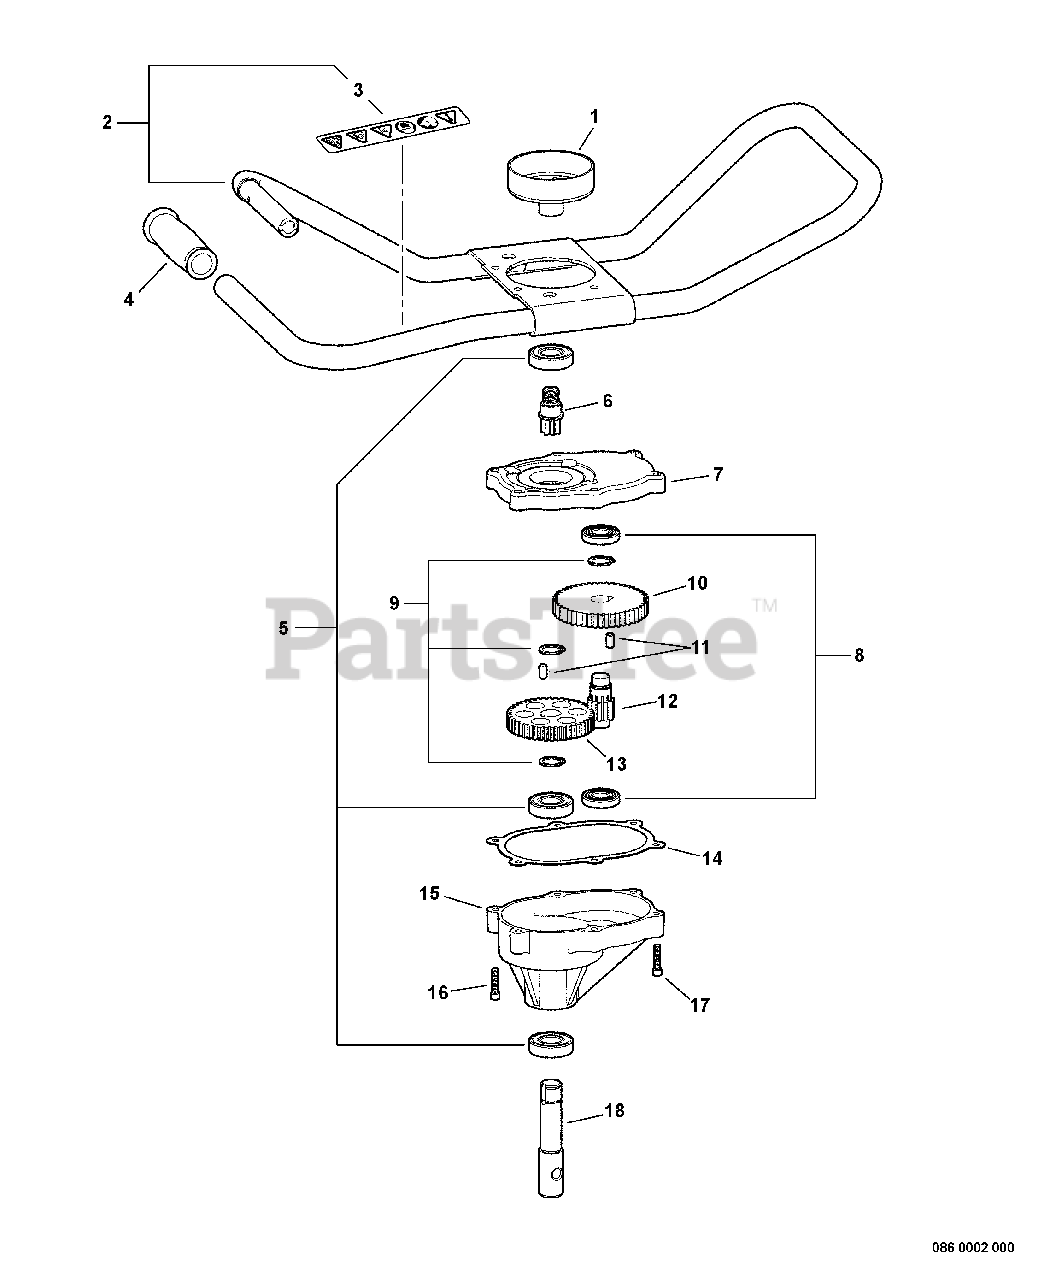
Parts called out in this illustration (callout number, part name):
1	DRUM, CLUTCH
2	HANDLE ASSY
3	LABEL, CAUTION
4	GRIP, HANDLE
5	BEARING, BALL
6	SHAFT, GEAR
7	CASE, GEAR
8	BEARING, BALL
9	RING, SNAP
10	GEAR, SPUR
12	SHAFT, GEAR
13	GEAR, SPUR
14	GASKET, GEAR CASE
15	COVER, GEAR CASE
18	DRIVESHAFT
